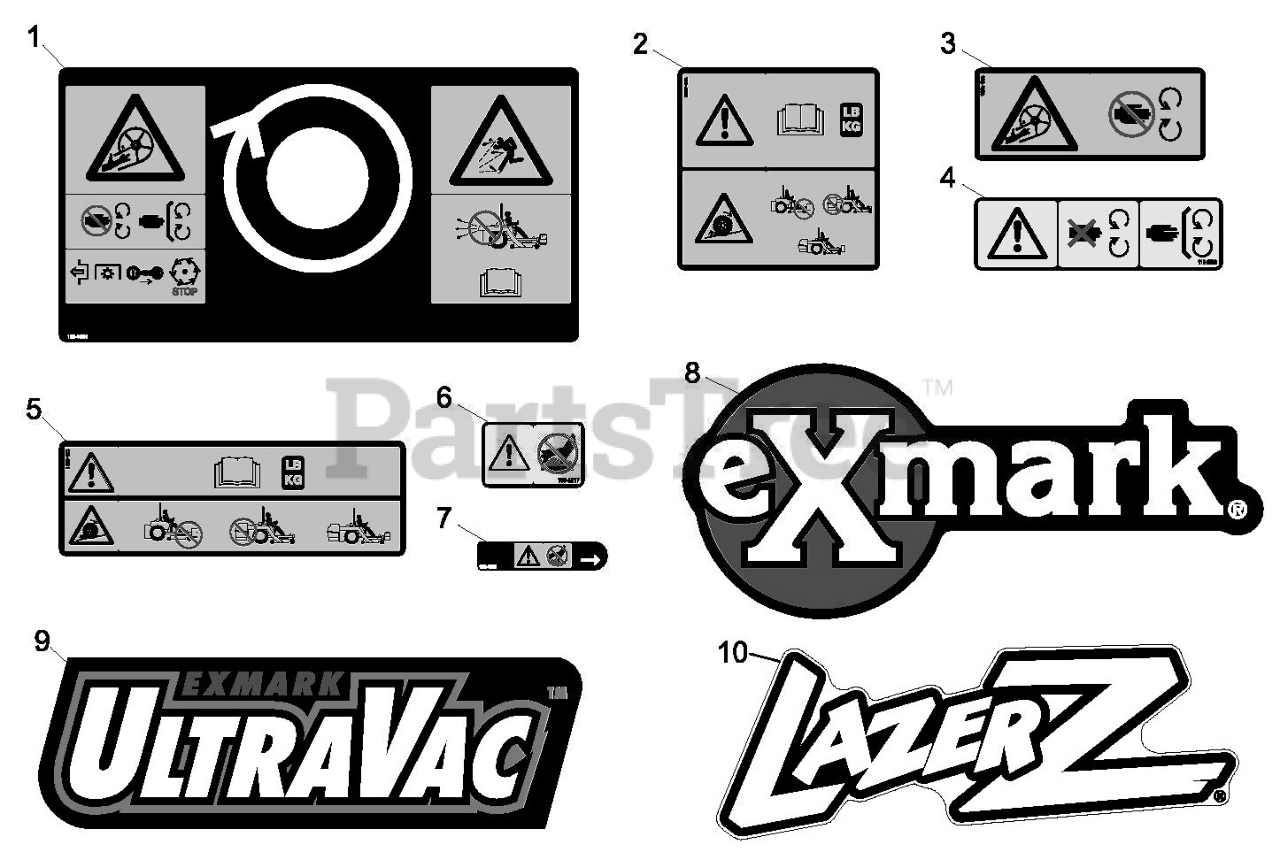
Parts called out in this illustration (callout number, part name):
1	Decal-Warning Blower
2	DECAL-WARNING, TRACTION
3	Decal-Blower Impeller Hazard
4	DECAL-COVER, MISSING
5	DECAL-WARNING WEIGHT
6	DECAL-WARNING
7	DECAL-WARNING
8	DECAL, EXMARK LOGO
9	DECAL, ULTRAVAC
10	DECAL,LAZER MODEL
